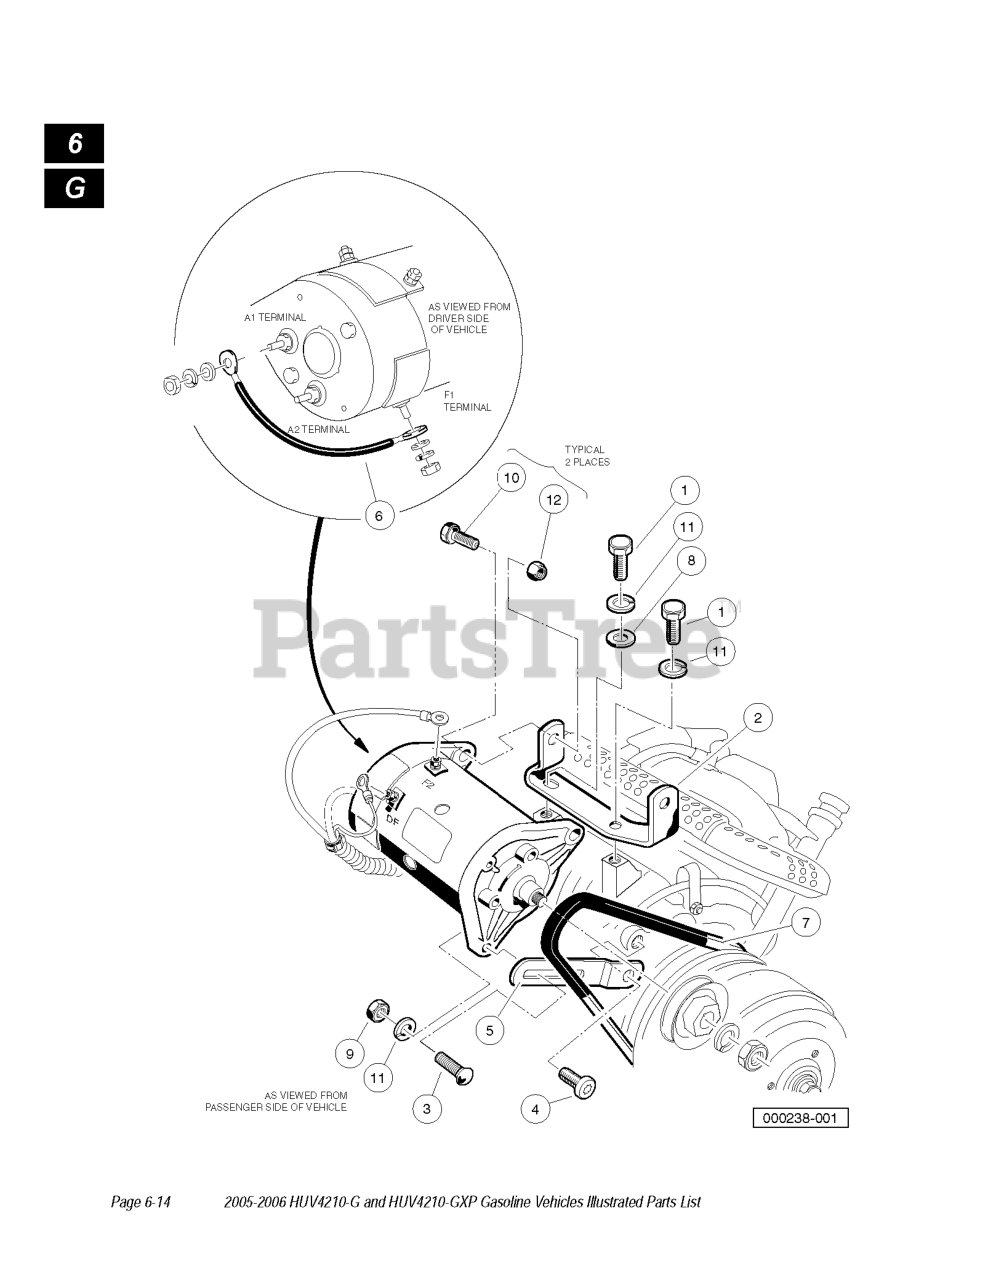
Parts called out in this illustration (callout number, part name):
1	SCREW, M8-125 X 22 HEX GR.8.8
2	BRACKET, FE290 S/G MOUNTING
3	BOLT, 5/16-18 RD HD SQ NECK
4	SCREW, M8-1.25 X 18MM TORX
5	BRACKET, S/G-ADJUSTABLE
6	WIRE ASSY, #6 GREEN
7	BELT, STARTER-GENERATOR
8	WASHER, 5/16 TYPE A FLAT
9	NUT, 5/16-18 HEX
11	LOCKWASHER, 5/16 SPLIT
12	LOCKNUT, 3/8-16 HEX
